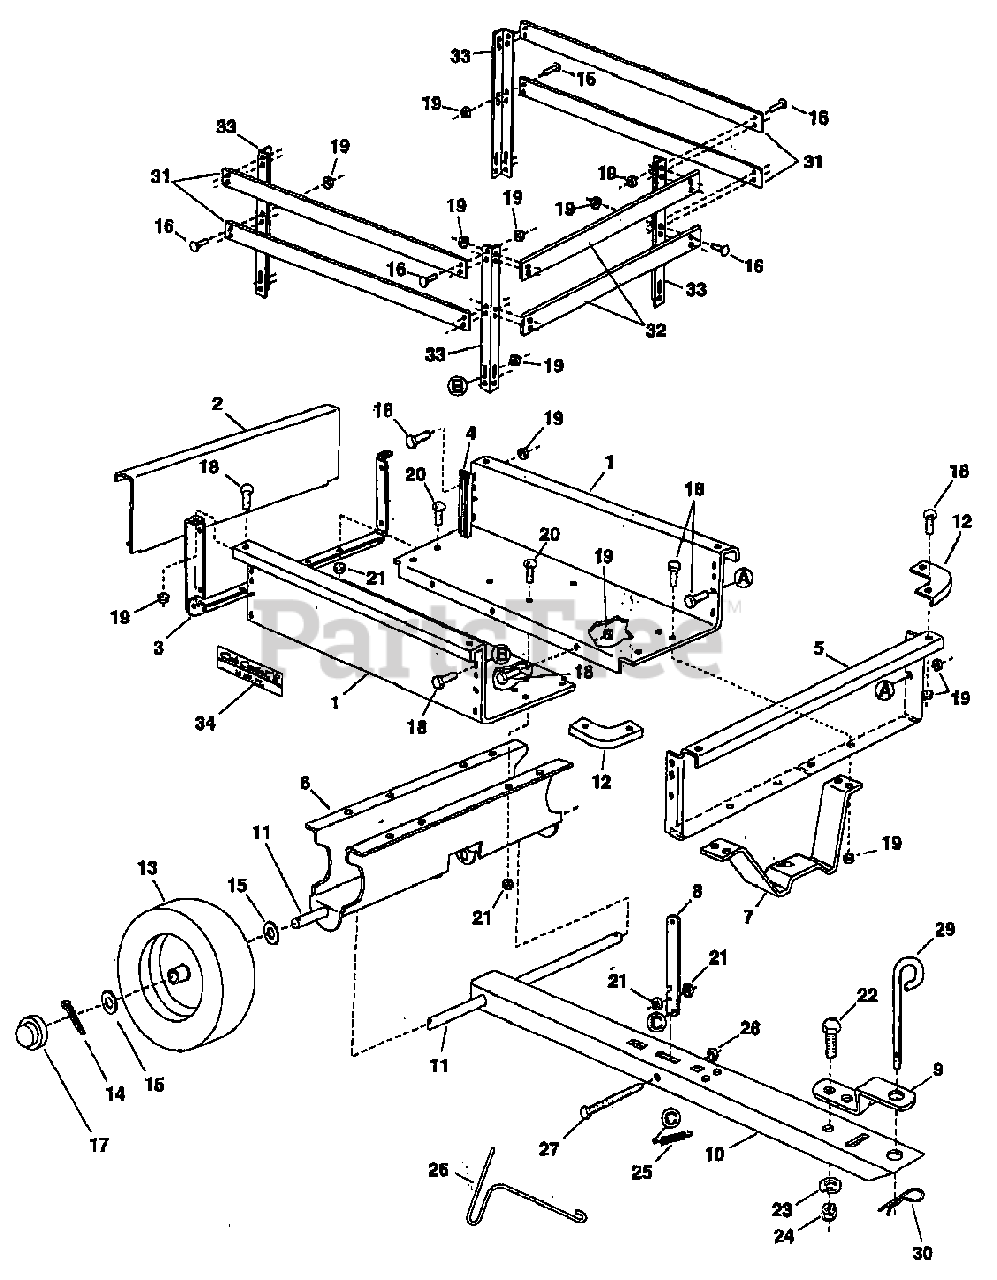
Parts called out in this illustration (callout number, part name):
8	Latch Lock Lever
10	Draw Bar Tongue
11	Axle, Wheel 3/4" Dia.
14	Cotter Pin, 1/8" Dia. x 1"
19	Hex Nut, 1/4-20 (SEMS)
20	Truss Hd. Bolt, 5/16-18 x 3/4" Lg.
21	Hex Nut, 5/16-18 (SEMS)
22	Hex Bolt, 3/8-16 x 1" Lg.
23	Look Washer, 3/8"
24	Hex nut, 3/8-16
25	Extension Spring
26	Spring Puller
28	Hex Lock Nut, 5/16-18
29	Hitch Pin
30	Hair Cotter Pin, 1/8" (#4)
31	Side Board
32	Front Board
33	Angle Bracket
